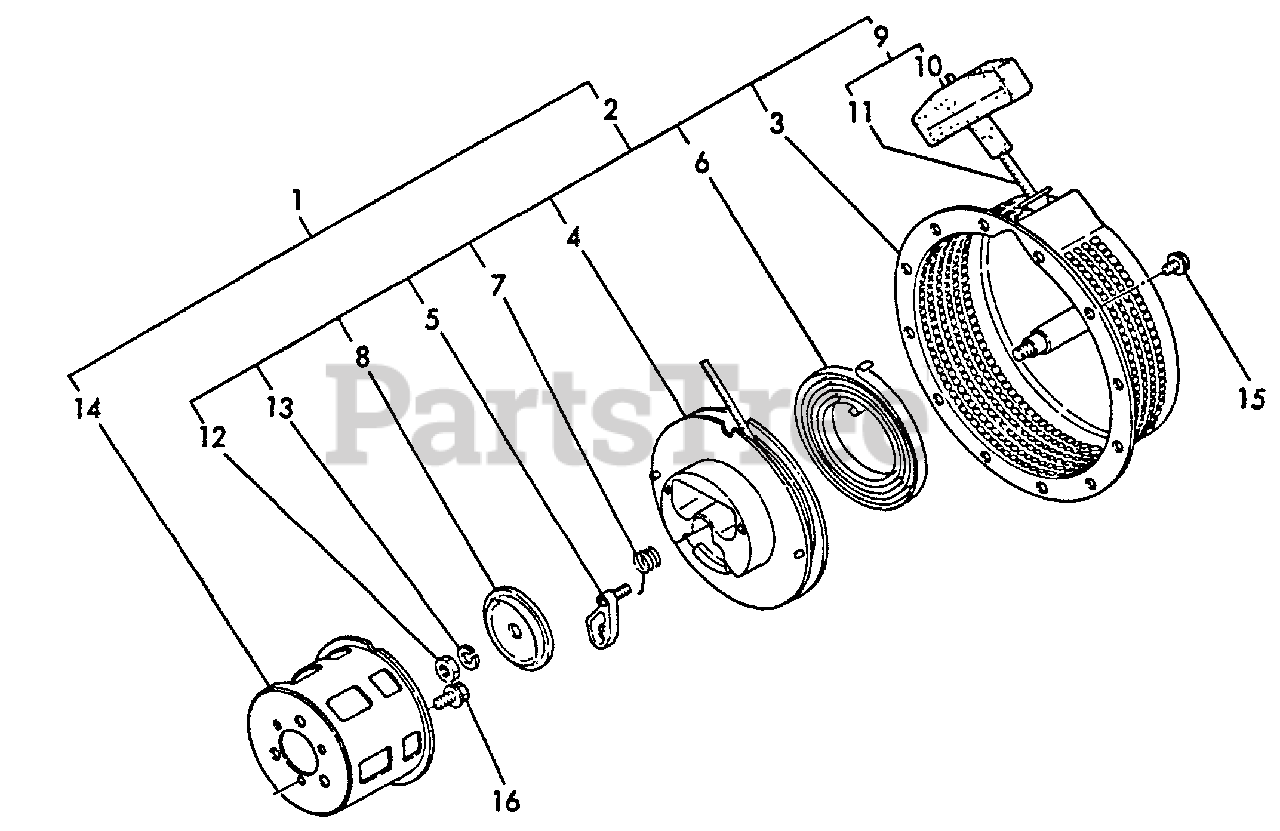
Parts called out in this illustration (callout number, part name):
1	STARTER ASSY
2	STARTER ASSY
3	CASE, STARTER
4	PULLEY
5	RATCHET
7	SPRING, FRICTION
8	PLATE, FRICTION
9	ROPE ASSY
10	GRIP, STARTER
11	ROPE, STARTER
12	NUT
13	LOCKWASHER
14	PULLEY, STARTER
15	BOLT - 6X8 -- PLATED
16	BOLT - 6X12 -- PLATED
